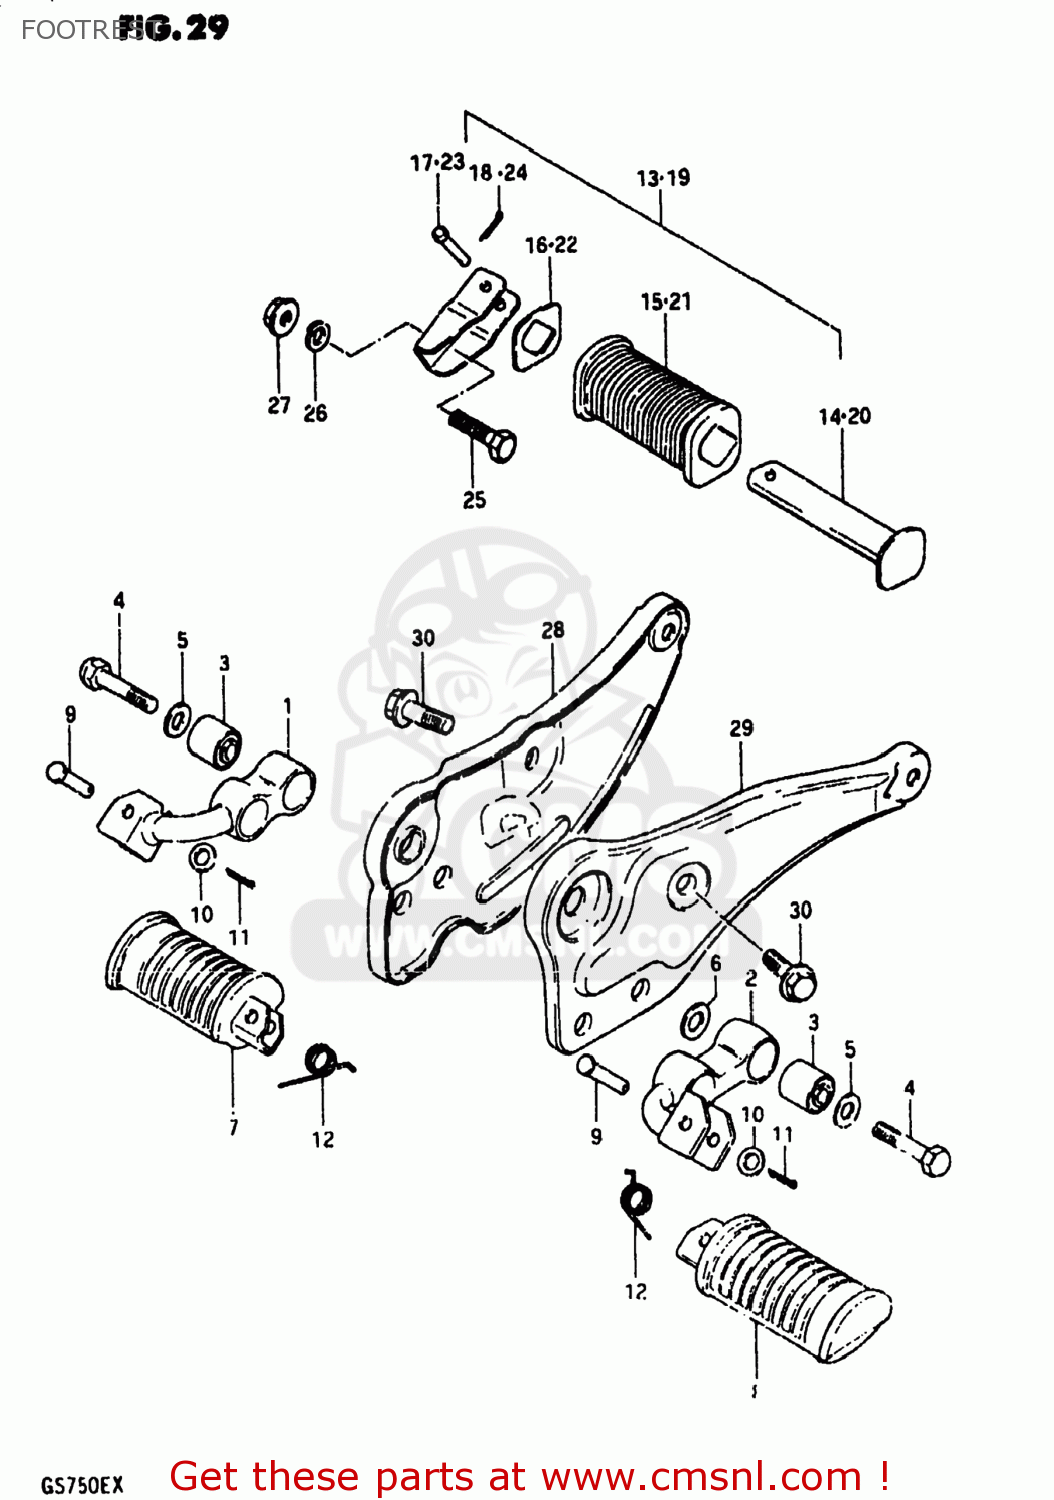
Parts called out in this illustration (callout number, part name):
1	BAR,FRONT FOOTREST
2	BAR,FRONT FOOTREST,LEFT
3	BUSH
4	BOLT(10X50)
5	WASHER (10.1X21X2.3)
6	WASHER
7	RUBBER,FRONT FOOTREST
8	FOOTREST
9	PIN
10	WASHER
11	PIN
12	SPRING
13	FOOTREST ASSEMBLY,REAR
14	BAR,REAR FOOTREST
15	RUBBER,REAR FOOTREST
16	WASHER,FOOTREST RUBBER
17	PIN
18	PIN
19	FOOTREST ASSEMBLY,REAR,LEFT
20	BAR,REAR FOOTREST,LEFT
21	RUBBER,PILLION FOOTREST
22	WASHER,FOOTREST RUBBER
23	PIN
24	PIN
25	BOLT,M10X1.25X
26	LOCK WASHER
27	NUT
28	BRACKET
29	BRACKET,MUFFLER,LEFT
30	BOLT
